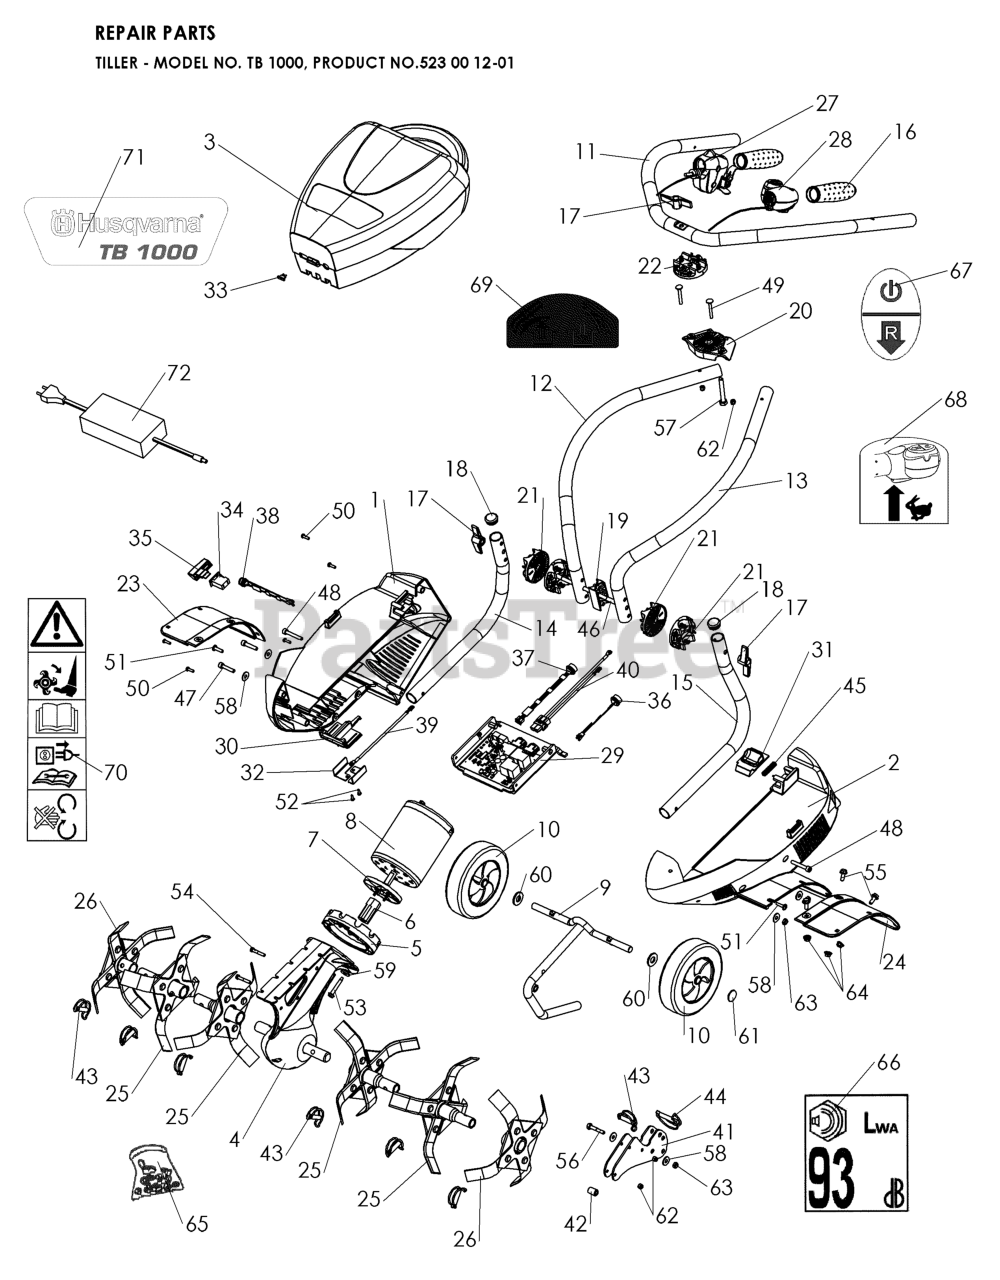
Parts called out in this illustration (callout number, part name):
3	BATTERY
4	TRANSMISSION
12	HANDLEBAR RIGHT
13	HANDLEBAR LEFT
14	HANDLEBAR RIGHT
15	HANDLEBAR LEFT
29	CONTROL BOARD
45	LOCKING SPRING
57	Screw HM 8x55 z cl 10.9
61	Starlock washer Ø12
63	Blocking nut M 6 Z
72	BATTERY CHARGER
